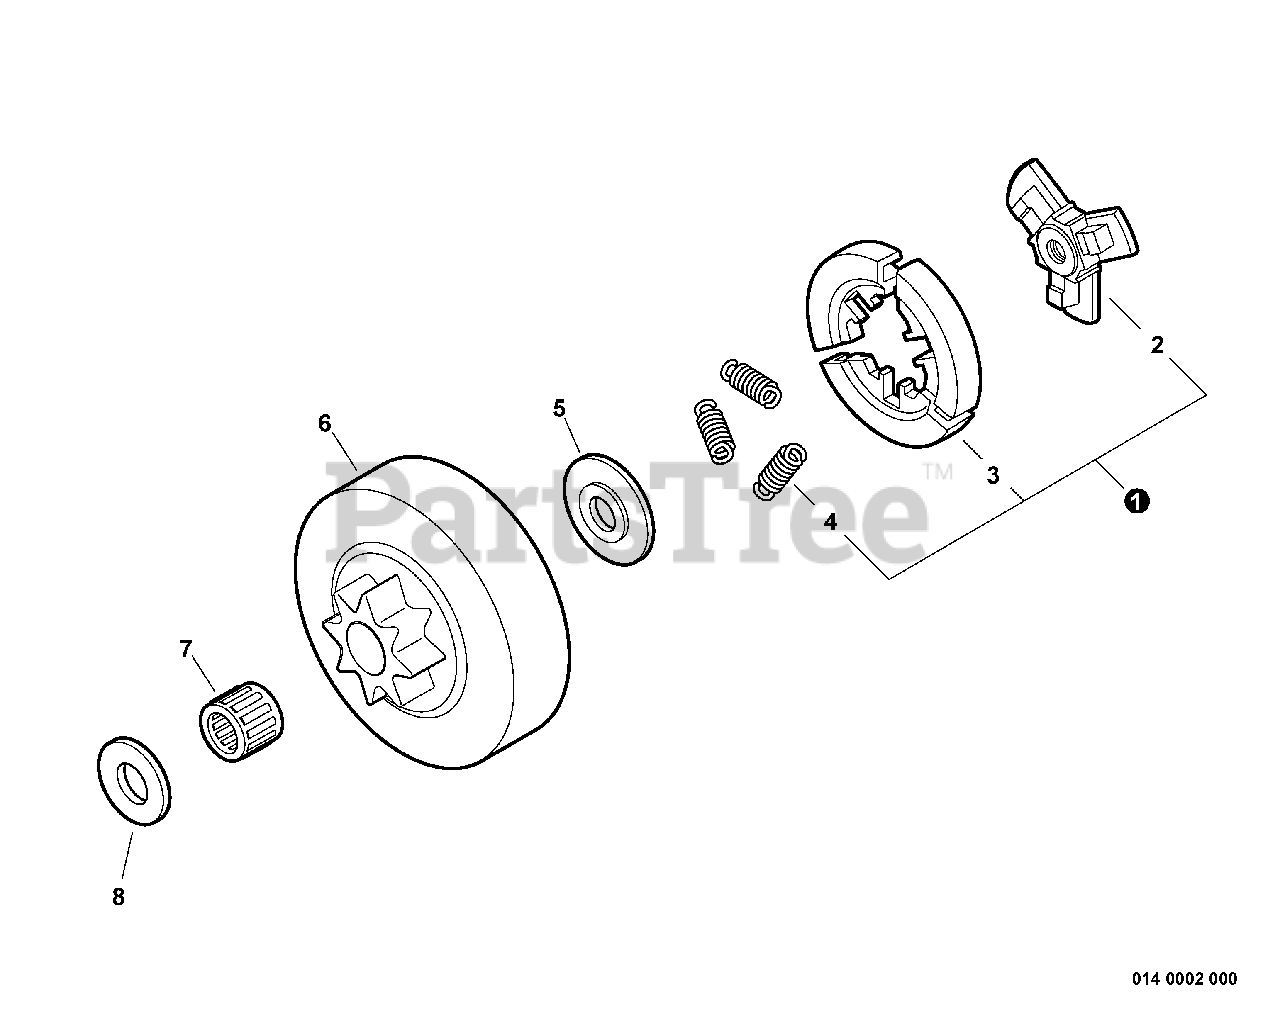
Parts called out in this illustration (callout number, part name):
1	CLUTCH ASSY
2	HUB, CLUTCH
3	CLUTCH SHOE SET
4	SPRING, CLUTCH
5	PLATE, CLUTCH
6	DRUM, CLUTCH
7	BEARING, NEEDLE
